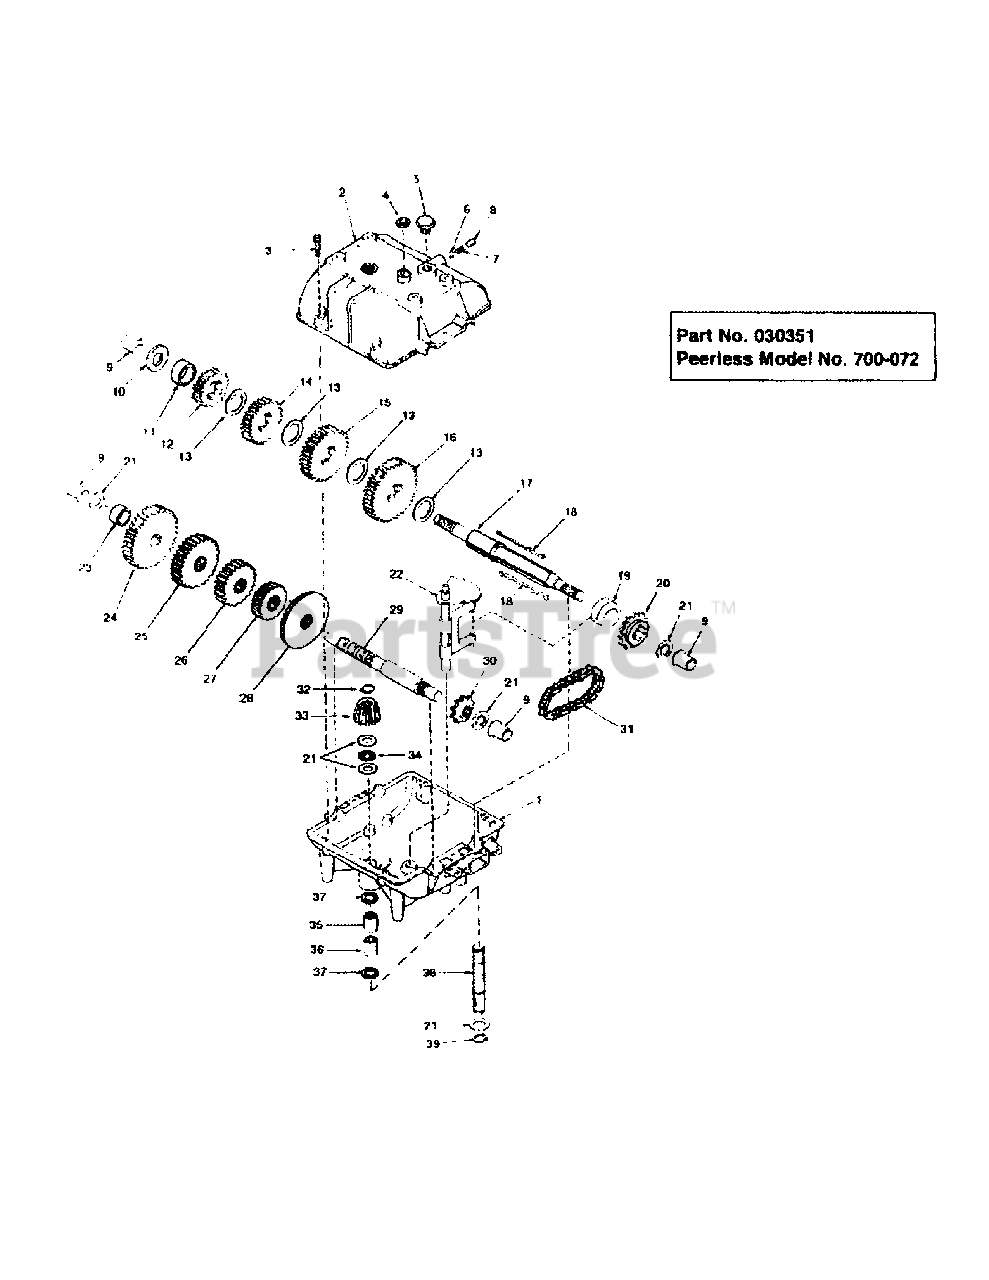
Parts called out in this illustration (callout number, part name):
1	transmission case
2	transmission cover
3	cap screw
4	seal, square cut
5	threaded plug
6	steel ball, 5/16" dia
7	spring
8	set screw
9	flange bushing
10	thrust washer
11	spacer
12	spur gear (30 teeth)
13	thrust washer
14	spur gear (32 teeth)
15	spur gear (35 teeth)
16	spur gear (37 teeth)
17	shaft-output/brake
18	key, shift
19	shift collar
20	sprocket (18 teeth)
21	thrust washer
22	rod & fork, shift
23	spacer
24	spur gear (20 teeth)
25	spur gear (18 teeth)
26	spur gear (15 teeth)
27	spur gear (12 teeth)
28	spur gear (42 teeth)
29	counter shaft
30	sprocket (9 teeth)
31	roller chain (#41, 24 links)
32	retaining ring
33	bevel pinion, input
34	thrust bearing
35	needle bearing
36	needle bearing
37	o-ring
38	input shaft
39	retaining ring
